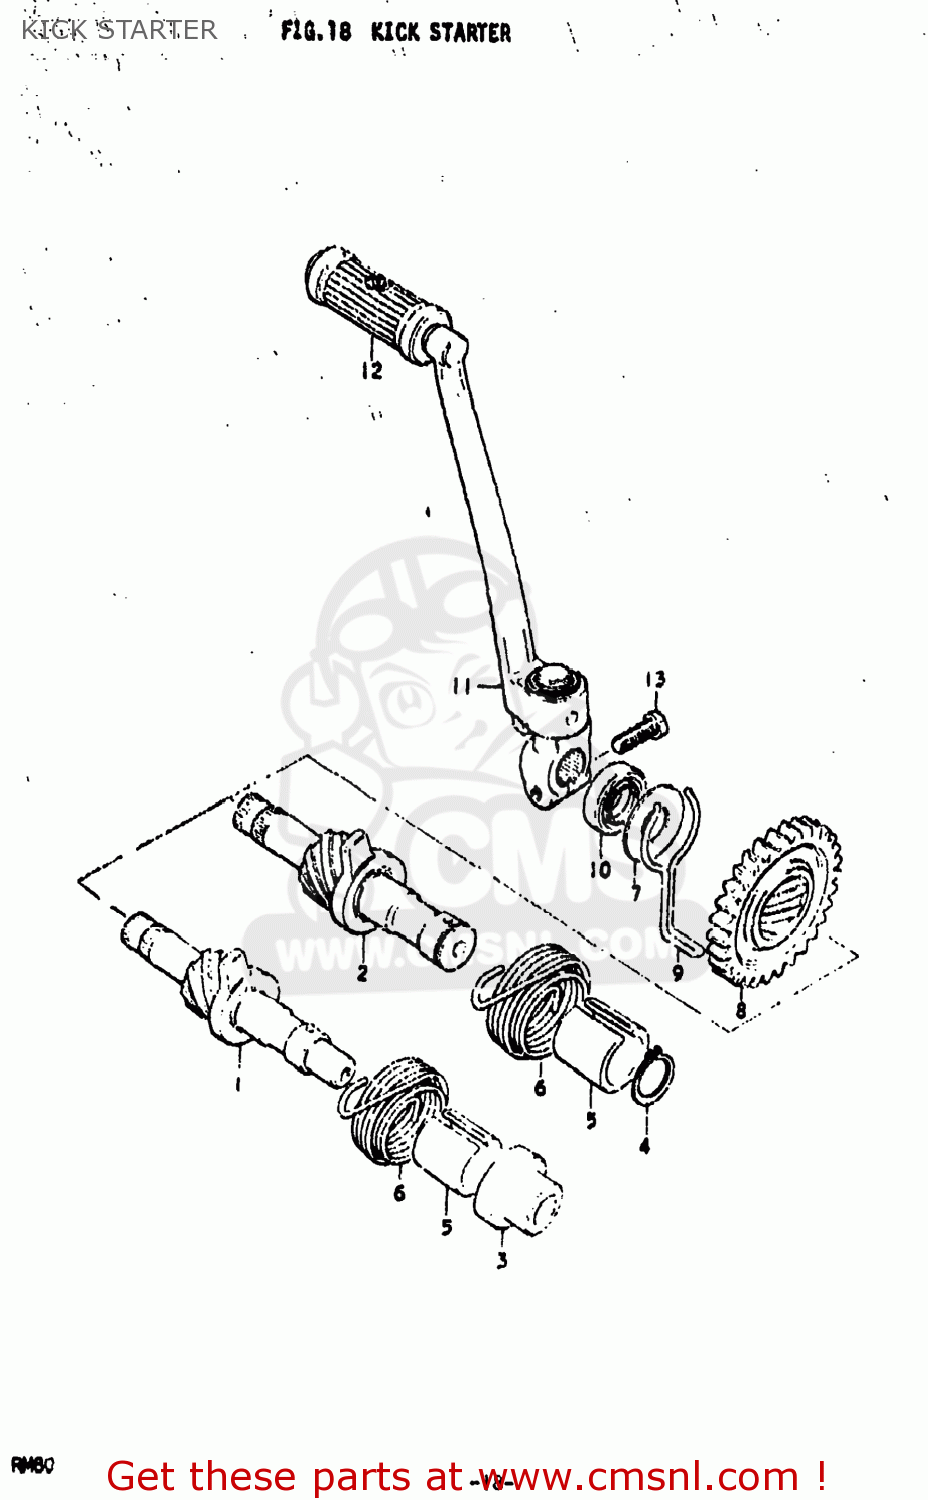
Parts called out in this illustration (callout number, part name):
1	SHAFT,KICK STARTER
2	SHAFT,KICK STARTER
3	HOLDER,KICK STARTER SHAFT
4	CIRCLIP,16MM
5	GUIDE,KICK STARTER SFT SPRING
6	SPRING
7	WASHER
8	GEAR,KICK STARTER DRIVE(NT:30)
9	RETAINER,SNAP
10	SEAL,OIL(14X24X6)
11	LEVER ASSEMBLY,KICK STARTER
12	RUBBER,KICK STARTER PEDAL
13	BOLT
